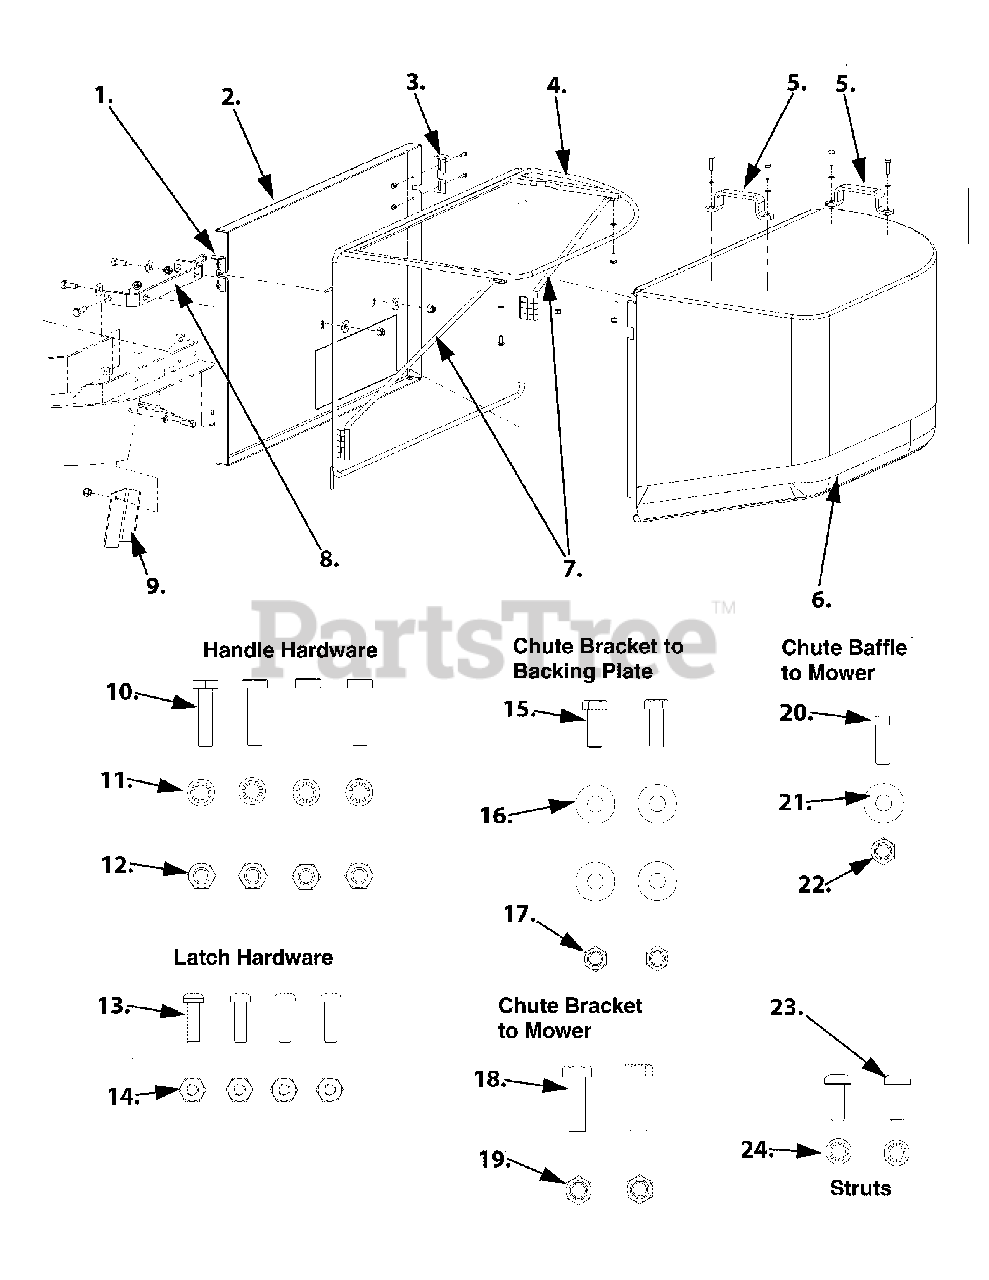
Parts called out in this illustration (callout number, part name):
2	Backing Plate
4	Bag Frame
6	Cloth Bag
7	Struts
8	Mounting Bracket
11	Internal Tooth Washers
12	Nylock Nuts 1/4-20
13	Pan Head Screws 10-32 x 5/8
14	Nylock Nuts 10-32
15	Screw, Hex Cap, 3/8-16 x 1.00
16	Flat Washers 3/8
17	Nylock Nuts 3/8-16
18	Screw, Hex Cap, 3/8-16 x 1.25
19	Nylock Nuts 3/8-16
20	Screw, Hex Cap, 5/16-18 x 1.00
21	Flat Washers 5/16
22	Nylock Nuts 5/16-18
23	Screw 1/4-20 x 5/8
